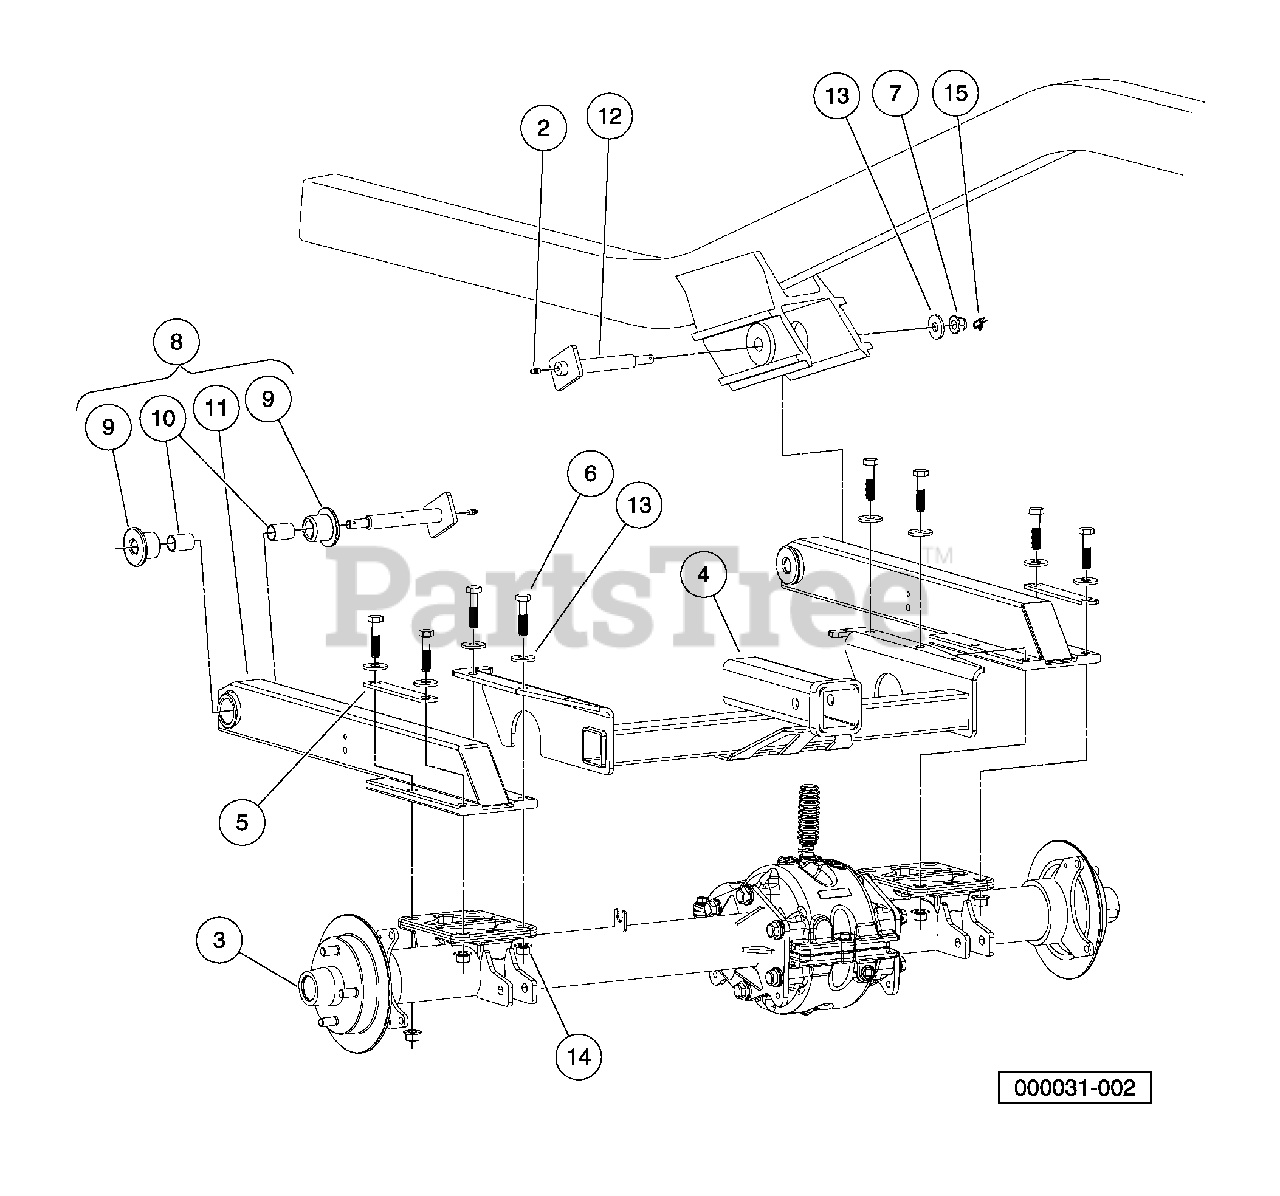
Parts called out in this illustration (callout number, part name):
1	Instl, Rear Suspension
2	Fitting, 1/4-28 Thread-Forming Grease
3	Center Cap, Rubber
4	Weldment, Receiver, Rear
5	Washer, Strip, Swingarm
6	Bolt Flanged Head, M12 X 1.75 X 50
7	Nut Flg, M12x1.75, Nylon Gr 10
8	Sub Asm Swingarm
9	Bushing, Pivot, Urethane
10	Bushing, Teflon
11	Swingarm, Rear, Awd
12	Pin, Swingarm, Weldment
13	Washer, M12 Hard Regular
14	Nut Flg M12 X 1.75 Cl10
15	Cotter, Rue Ring, 1/2"
